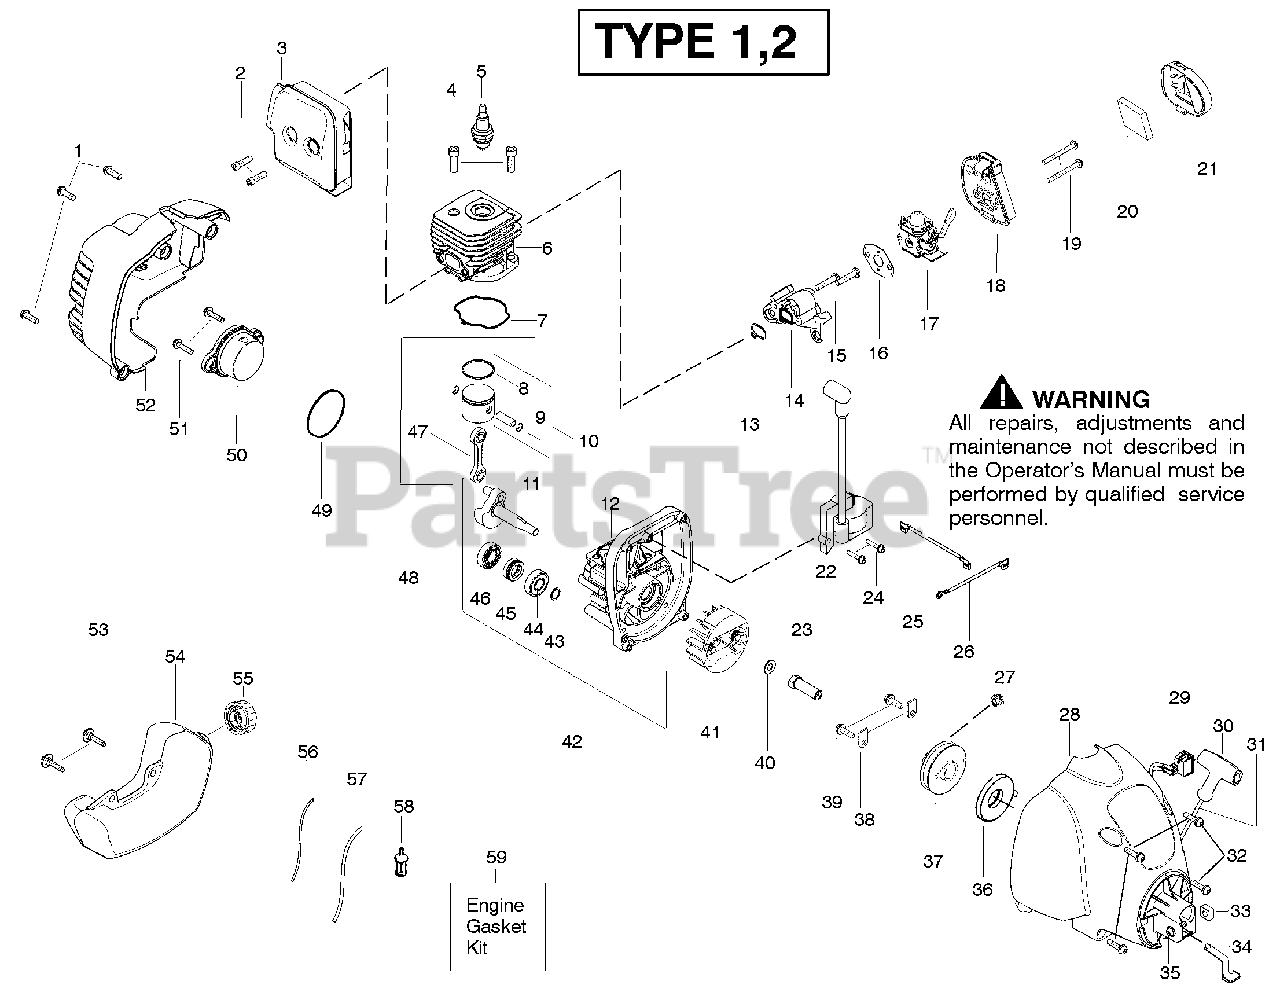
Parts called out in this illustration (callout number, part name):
2	Bolt-Muffler
3	Assy-Muffler/Shield
4	Screw-Cylinder
5	Spark Plug (RCJ 6Y)
6	Cylinder
7	Seal-Cylinder (kit)
8	Piston Ring
9	Retainer-Piston Pin
10	Kit - Piston
11	Assy-Crankshaft
12	Assy-Crankcase
13	Seal-Cyl/Carb.(kit)
14	Adapter-Carb.
16	Gasket-Carb. (kit)
17	Kit-Carb. Zama (C1U-W18)
17	Kit-Carb. Walbro (WT-669)
18	Air Box
20	Foam-Air Filter
21	Cover-Air Box
22	Ignition Module
23	Coupling-Drive
25	Assy-Leadwire
26	Assy-Ground Wire
28	Assy.-Fan Hsg
29	Kit-Switch
30	Handle-Starter
31	Kit - Rope
32	Screw
34	Clip-Spring
36	Spring-Starter
37	Kit-Pulley-Starter
38	Retainer-Pulley
40	Washer-Flat
41	Assy-Flywheel
42	Assy-C'case & C'shaft
43	Retain. Ring-C'shaft
44	Outer Bearing
45	Seal-C'case
46	Inner Bearing
47	Assy-Connecting Rod
48	Kit-piston/rod
49	O-Ring-C'case (kit)
50	Assy-Plug
52	Shroud-Rear Green
53	Retainer-Tank
54	Assy-Fuel Tank
55	Assy-Fuel Cap
56	Kit-Fuel Line (Small)
57	Kit-Fuel Line (Large)
58	Assy-Fuel Pickup
59	Kit-Engine Gasket
